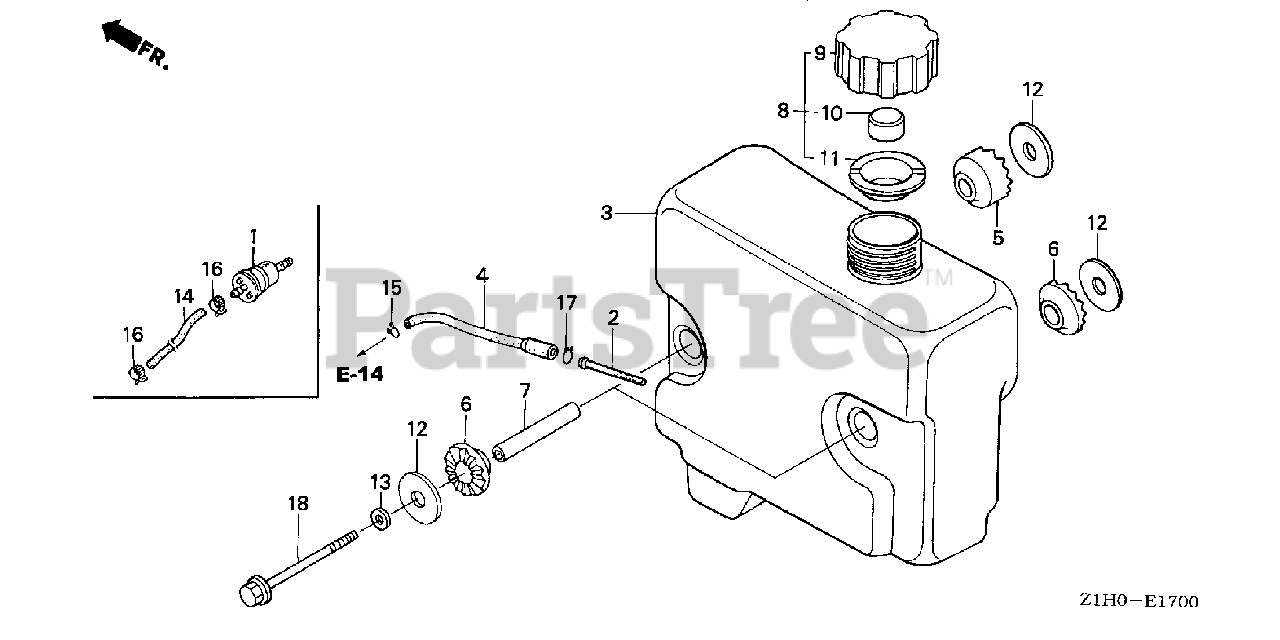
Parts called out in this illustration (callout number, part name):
1	STRAINER, FUEL
14	BULK HOSE, FUEL (4.5X3000) (4.5X360)
16	CLAMP, TUBE (D8.5)
